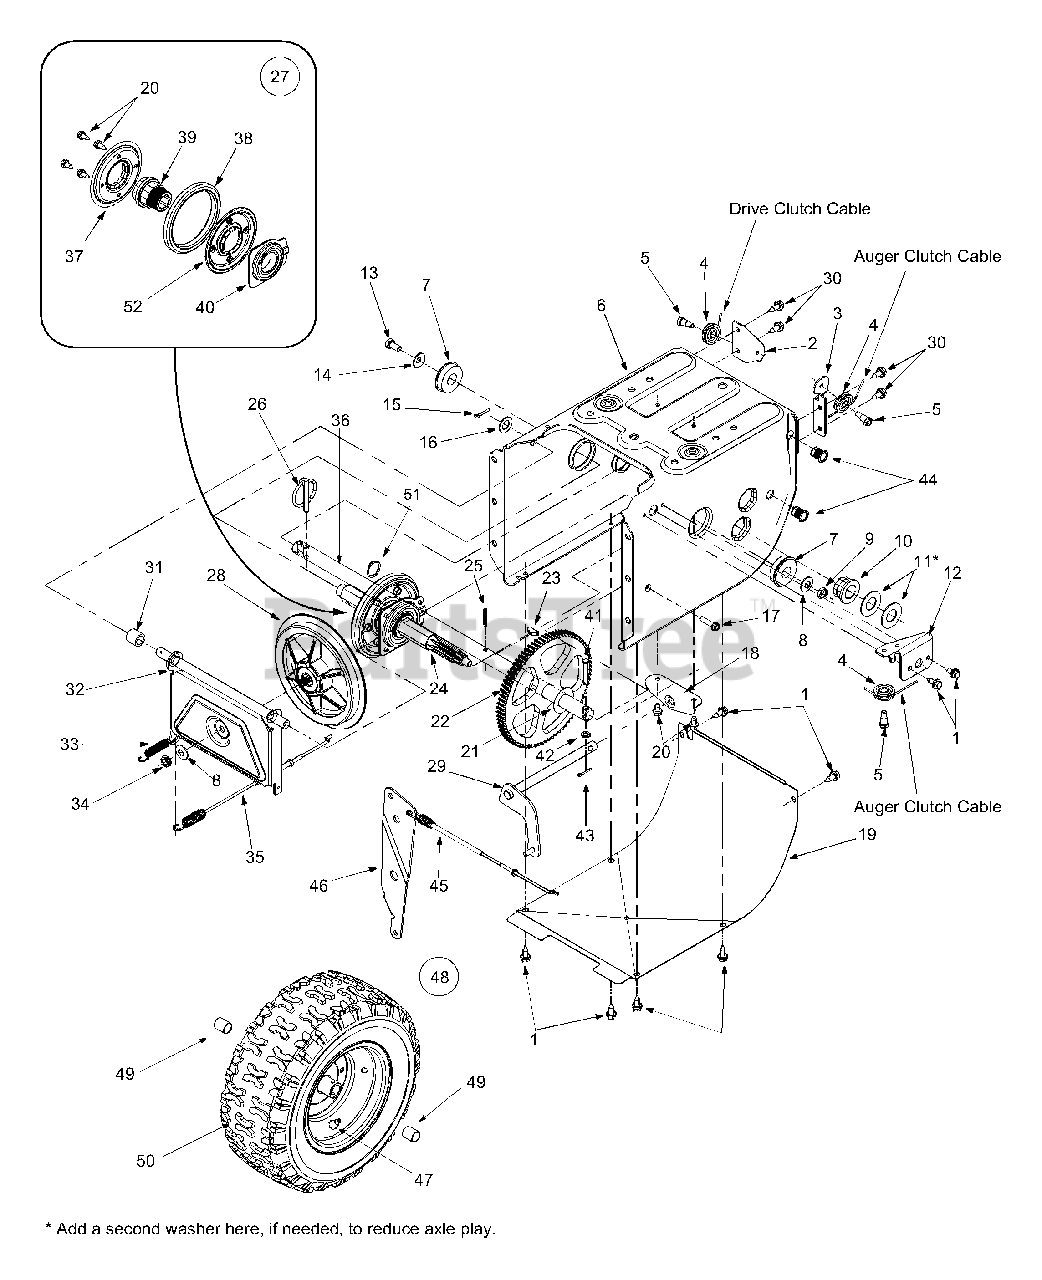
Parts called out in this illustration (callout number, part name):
1	Self-tapping Screw, 1/4-20 x .625
5	Hex Screw 1/4-28
6	Frame Assembly
7	Ball Bearing
8	Bell Washer
9	Lock Jam Nut
10	Hex Flange Bearing
11	Flat Washer
14	Bell Washer .340 ID x .872 OD
15	Cotter Pin
16	Flat Washer .536 ID x .930 OD
17	Self-tapping Screw, 1/4-20 x 1.25
21	Flat Washer .760 ID x .50 OD
24	7-Tooth Shaft
25	Roll Pin
26	Klik Pin
27	Friction Wheel Assembly
28	Friction Disc Wheel
29	Wheel Shift Rod Assembly
30	Self-tapping Screw, 1/4-20 x .5
31	Spacer
34	Jam Nut 3/8-24
35	Drive Cable, Clutch
36	Axle (E663H)
36	Axle (E643E)
37	Friction Plate
38	Friction Wheel Rubber
39	Friction Wheel Hub
40	Friction Wheel Bearing
41	Clevis Pin, 1/4 x 1.3725
42	Flat Washer, .281 x .5 x .063
43	Cotter Pin, .75
44	Insert Nut, 5/16-18
45	Drive Cable, Auger
47	Air Valve
50	Tire Only, 16 x 6.5 x 8 (E663H)
51	Snap Ring
52	Friction Plate
